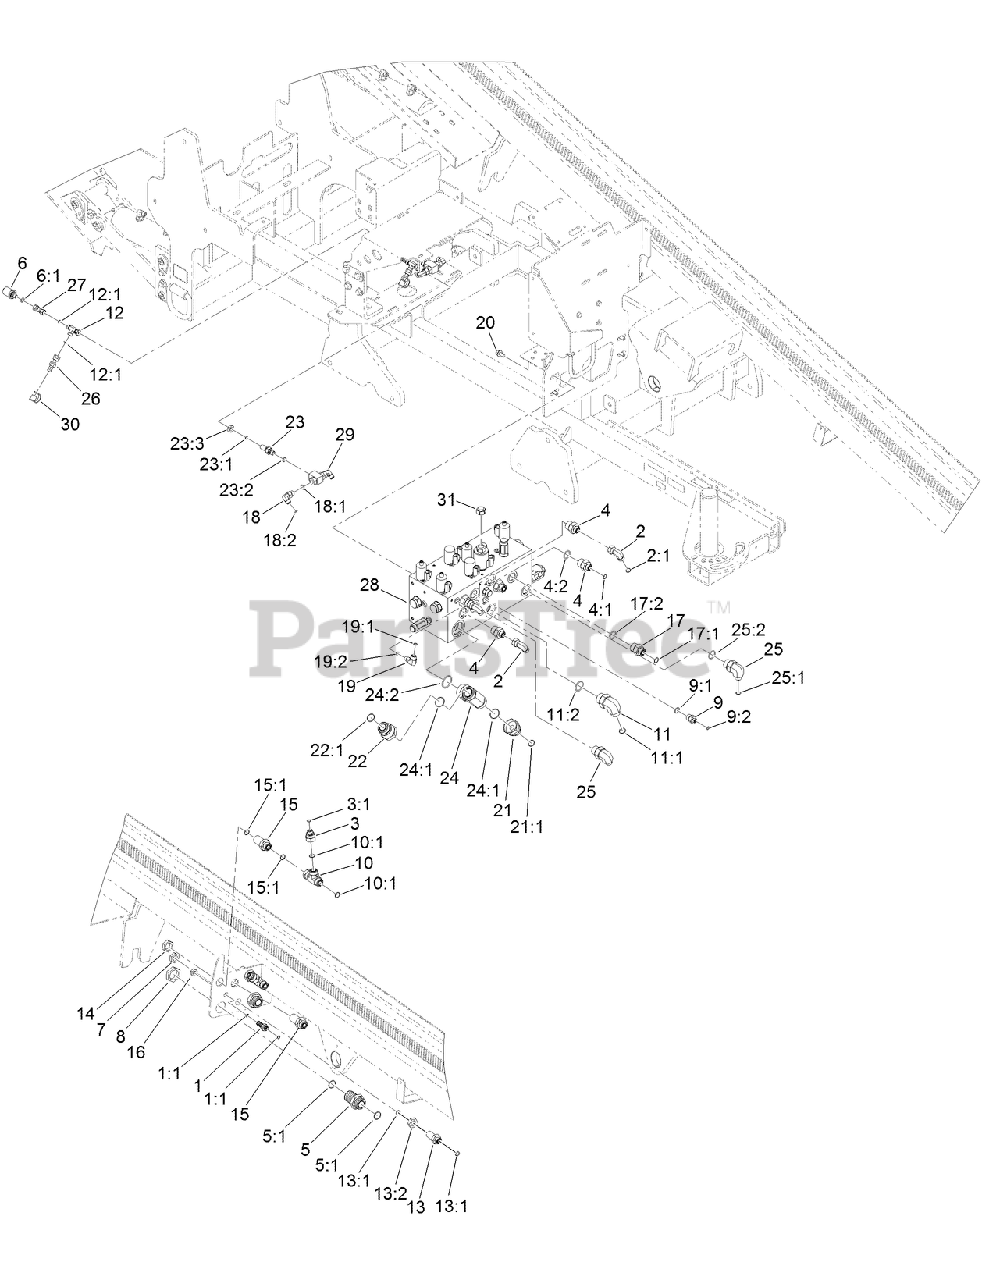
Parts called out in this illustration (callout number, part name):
1	UNION-BULKHEAD
1:1	O-RING
2	FITTING-HYD
2:1	O-RING
3	FITTING-HYD
3:1	O-RING
4	FITTING-STR
4:1	O-RING
4:2	O-RING
5	ADAPTER-HYD
5:1	O-RING
6	TRANSDUCER
7	NUT-BULKHEAD
8	NUT-BULKHEAD
9	FITTING-STR
9:1	O-RING
9:2	O-RING
10	FITTING-HYD, TEE
10:1	O-RING
11	FITTING-ELBOW 90
11:1	O-RING
11:2	O-RING
12	FITTING-HYD
12:1	O-Ring
13	FITTING-BULKHEAD
13:1	O-RING
13:2	NUT-BULKHEAD
14	NUT-LOCK, BULKHEAD
15	FITTING-BULKHEAD UNION, STRAIGHT
15:1	O-RING
16	NUT-LOCK
17	FITTING-STRAIGHT
17:1	O-RING
17:2	O-RING
18	FITTING-ELBOW 90
18:1	O-RING
18:2	O-RING
19	FITTING-ELBOW 90
19:1	O-RING
19:2	O-RING
20	SCREW-HHF
21	FITTING-STRAIGHT
21:1	O-RING
22	FITTING-REDUCER
22:1	O-RING
23	FITTING-STRAIGHT
23:1	O-RING
23:2	O-RING
23:3	NUT-LOCK
24	FITTING-TEE
24:1	O-RING
24:2	O-RING
25	FITTING-HYD, 90 DEG
25:1	O-RING
25:2	O-RING
26	NIPPLE-TEST
27	FITTING-STRAIGHT
28	4 SECTION HYD VALVE ASM
29	VALVE-SHUTTLE, LOAD
30	CAP-DUST
31	CAP-VALVE, ALUMINUM
